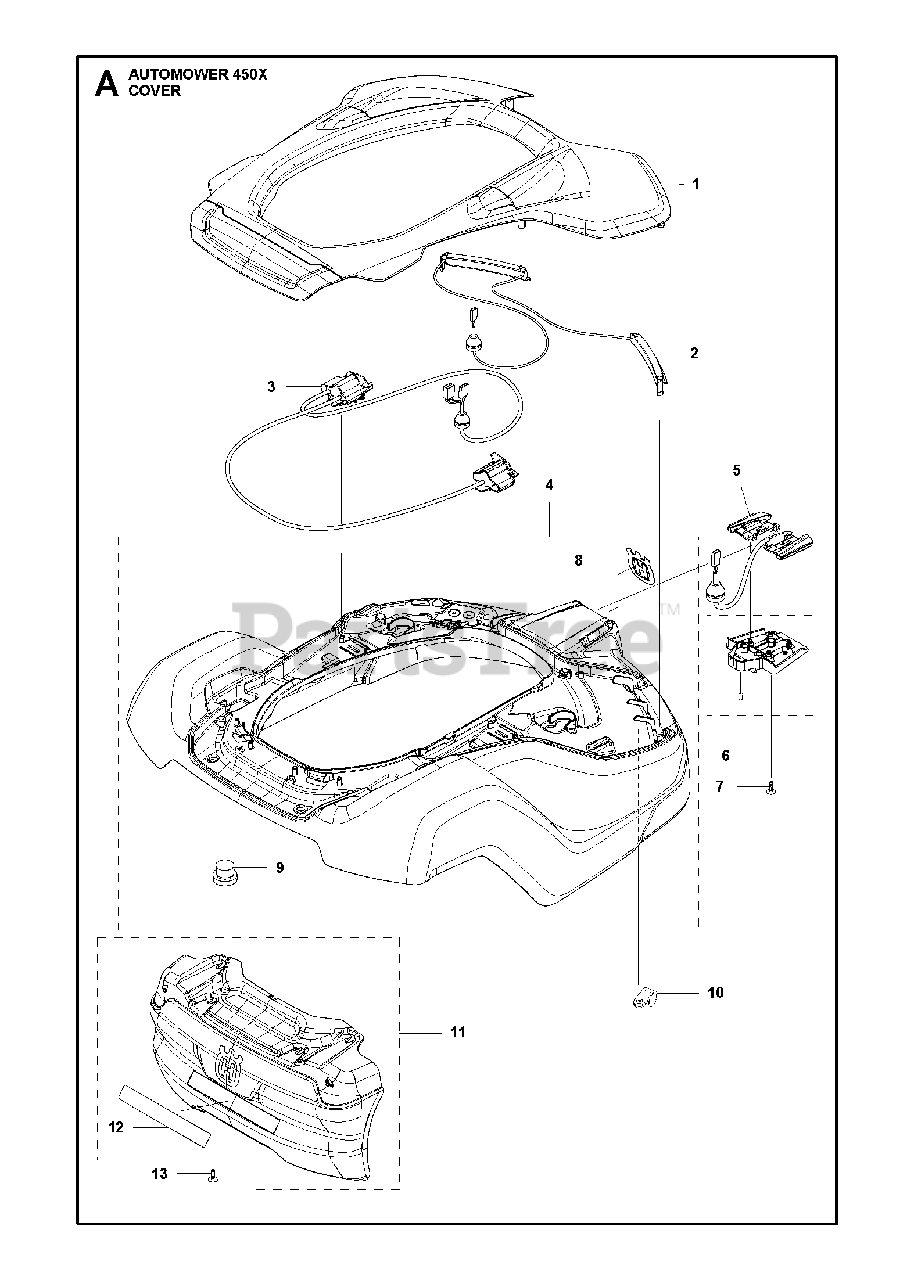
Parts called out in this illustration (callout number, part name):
1	BODY KIT
1	Top Cover, White 450
1	TOP COVER ORANGE 450
2	WIRING ASSY LED
3	WIRING ASSY ULTRASONIC
4	BODY ASSY
5	LOOM CHARGING PLATE
6	HOLDER ASSY MAGNET
7	SCREW 14MM
8	DECAL HUSQVARNA CROWN HEIGHT 5
9	CAP SNAPLOC
10	CLAMP P-CLIP
11	BUMPER ASSY
12	LABEL WARNING P15
13	SCREW ITXPANT
